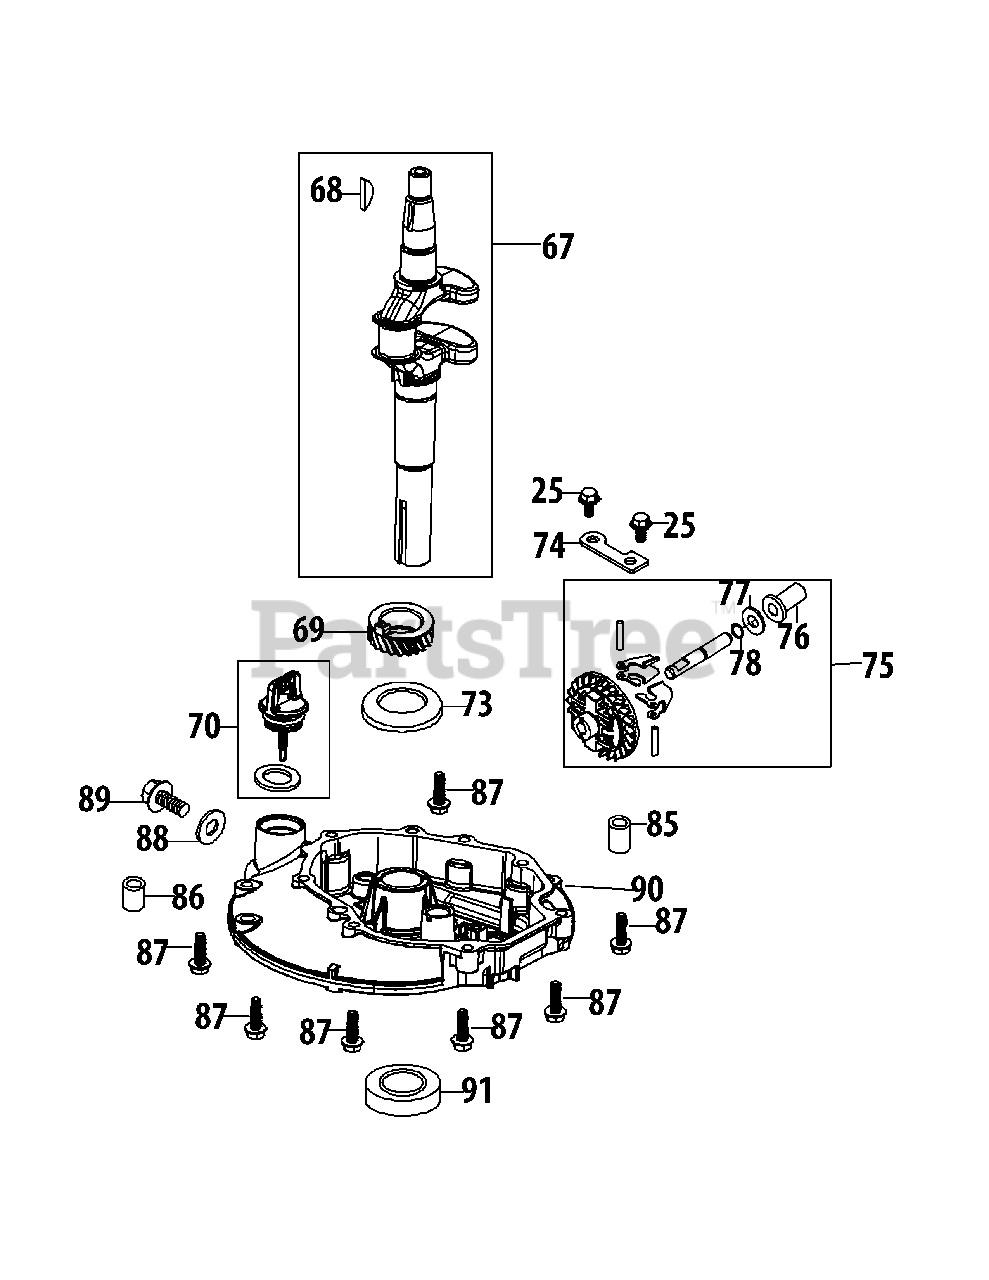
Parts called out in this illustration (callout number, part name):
25	Bolt M6X14 Multi-Purpose
67	Crankshaft Assembly
68	Flywheel Key
69	Timing Gear
70	Dipstick Assembly
73	Crankshaft Thrust Washer
74	Governor Gear Mounting Plate
75	Governor Gear/Shaft Assembly
76	Governor Slide Cap
77	Governor Slide Cap Washer
78	Governor Shaft Stop Ring
85	Crankcase Cover Dowel Pin 7×14
86	Crankcase Cover Dowel Pin 9×14
87	Bolt M6X28 T/X/P Multi-Purpose/Crankcase
88	Oil Drain Plug Washer
89	Oil Drain Plug
90	Crankcase Cover
91	Lower Crankshaft Seal
